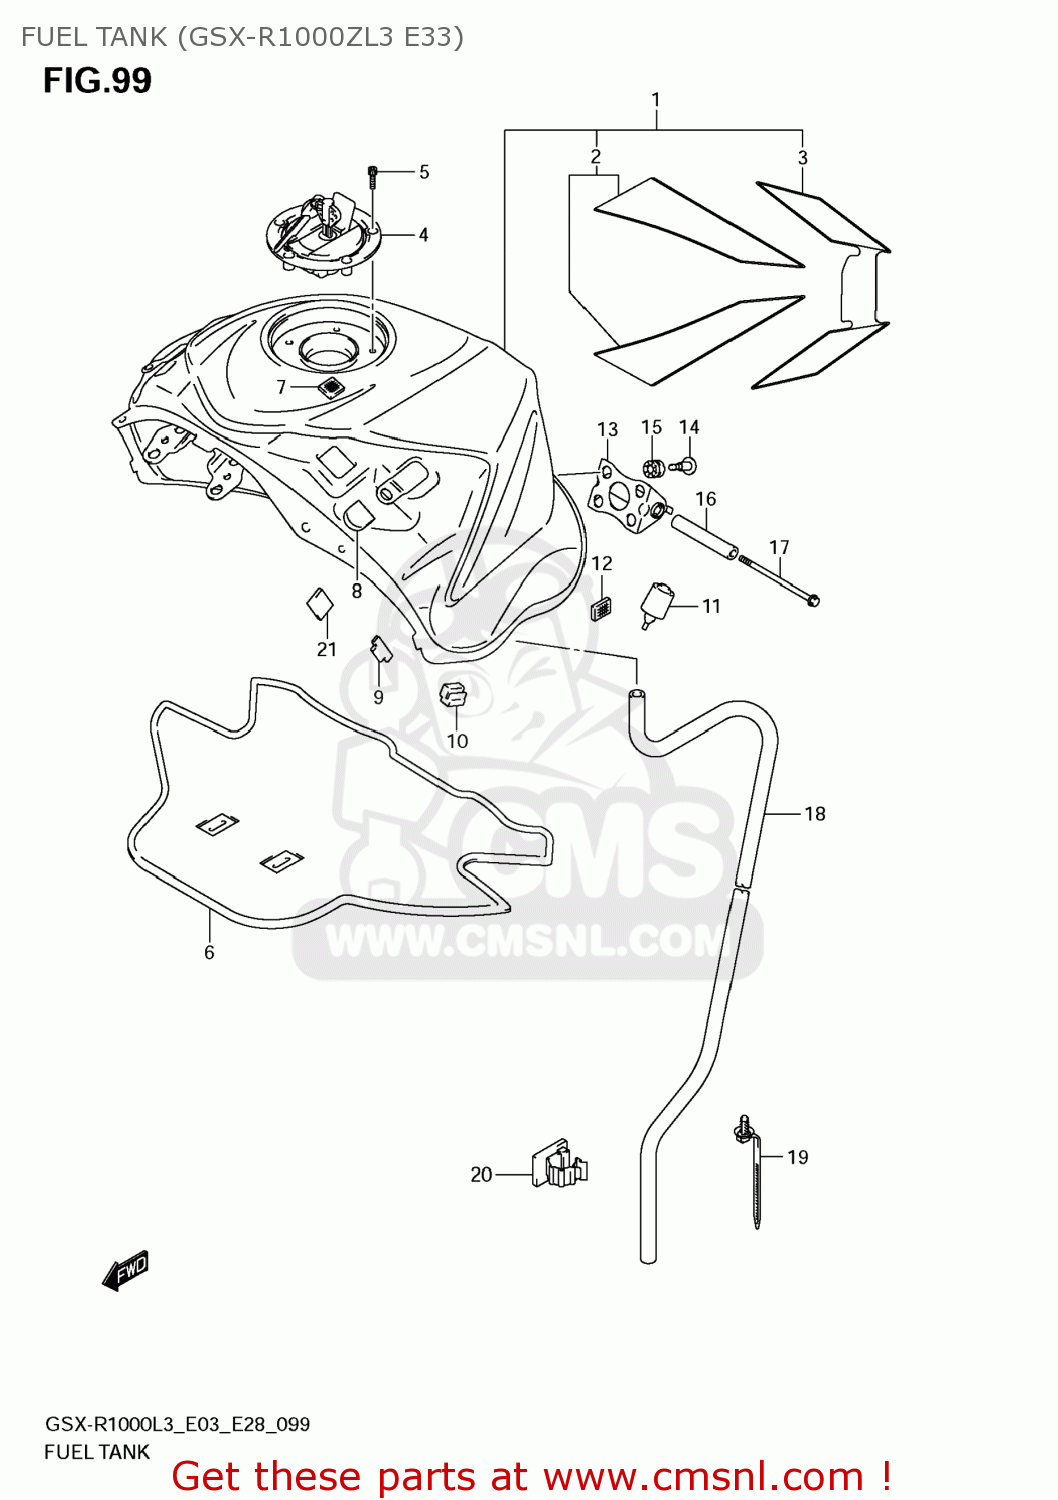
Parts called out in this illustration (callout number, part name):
1	TANK ASSY,FUEL(WHITE)
2	TAPE SET,FUEL TANK
3	TAPE,FUEL TANK CTR
4	CAP SET,FUEL TANK
5	BOLT(5X20)
6	SHIELD,FUEL TANK HEAT
7	FASTENER
8	CUSHION
9	CUSHION,FUEL TANK COVER
10	CUSHION,FUEL TANK SIDE
11	CUSHION,FUEL TANK RR
12	FASTENER
13	BRACKET,FUEL TANK NO.1
14	SCREW(6X22)
15	CUSHION
16	SPACER,FUEL TANK RR
17	BOLT(6X110)
18	HOSE,FUEL TANK WATER DRAIN
19	CLAMP(L:154)
20	CLAMP
21	PAD
